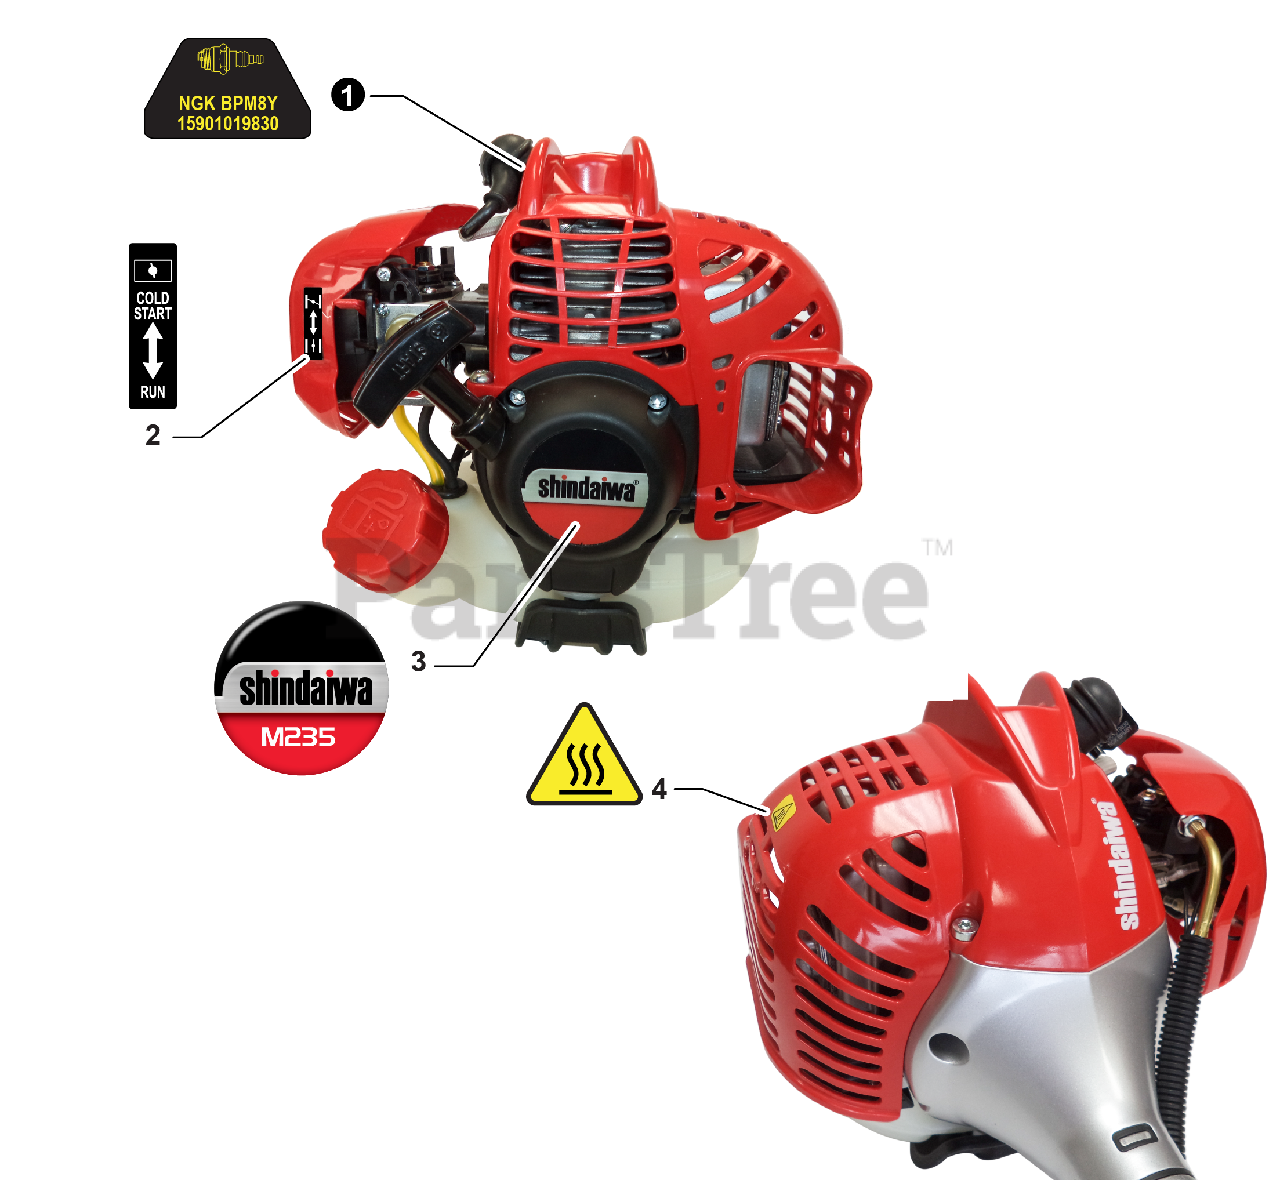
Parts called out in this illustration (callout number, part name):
1	LABEL, SPARK PLUG - BPM8Y
2	LABEL, CHOKE
3	LABEL, SHINDAIWA - M235
4	LABEL, CAUTION - HOT
